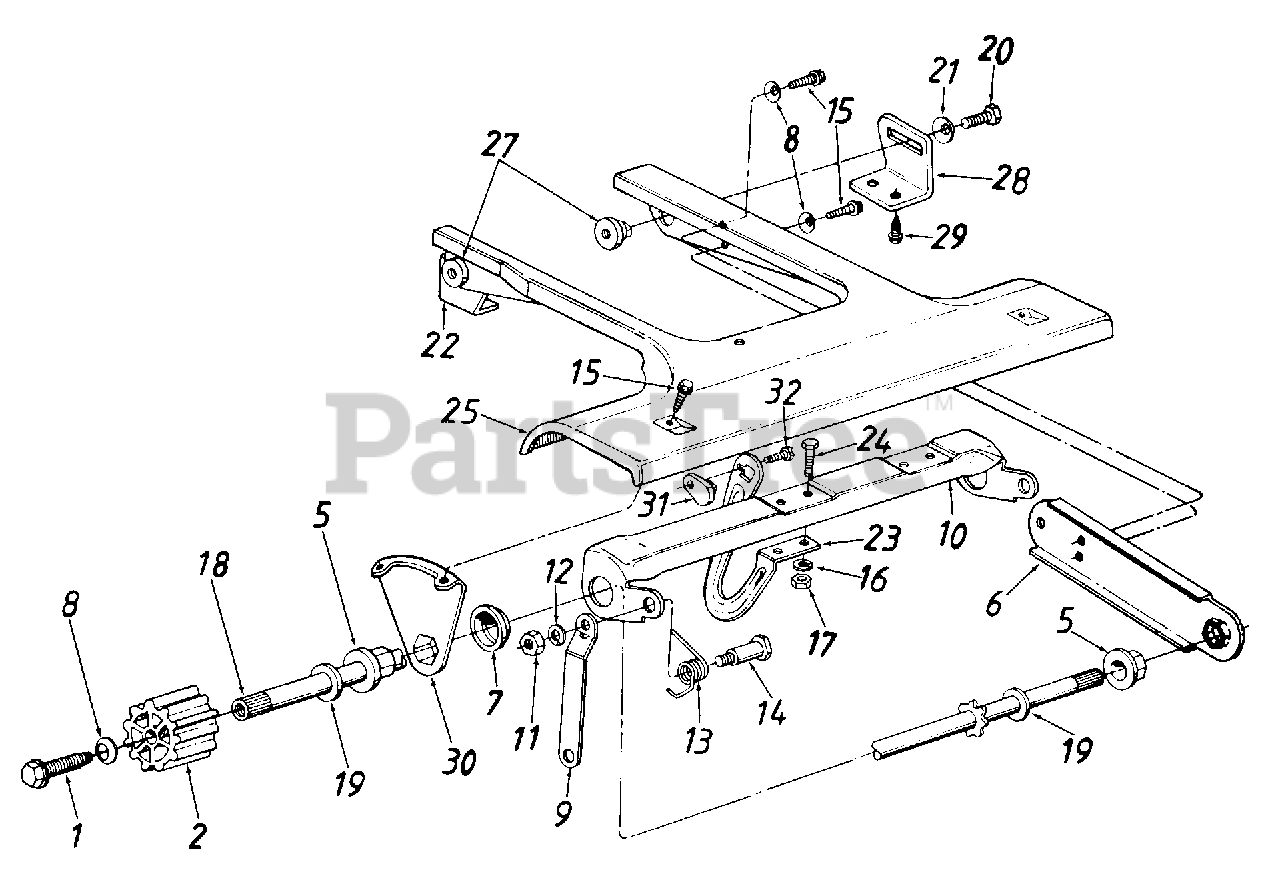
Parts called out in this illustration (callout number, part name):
1	Hex Wash. Hd. Tap Scr. 1/4-20 x .75" Lg.
2	Wheel Drive Pinion
5	Hex Flange Brg. .504" I.D.
8	Bell-Wash. .265" I.D. x .75" O.D.
9	Link 5.06" Lg.
10	Drive Engagement Cam
11	Hex Nut 5/16-18 Thd.*
12	L-Wash. 5/16" I.D.
13	Torsion Spring-R.H.
14	Shoulder Bolt .437" Dia.
15	Hex Wash. Hd. AB-Tap Scr. 1/4 x .62" Lq .
16	L-Wash. 1/4" I.D.*
17	Hex Nut 1/4-20 Thd.*
18	Drive Shaft Ass'y.
19	Fl-Wash. .531" I.D. x .93" O.D.
20	Hex Bolt 5/16-18 x .62" Lg.*
21	Bell-Wash. .345" I.D. x .88" O.D.
22	Pivot Bracket-R.H.
25	Front Pinion Pivot Cover
27	Shoulder Nut
28	Pivot Bracket-L.H.
29	Hex Wash. Hd. AB-Tap Scr. 1/4 x.62" Lg.
32	Hex B-Tap Scr. #10 x .44" Lg
